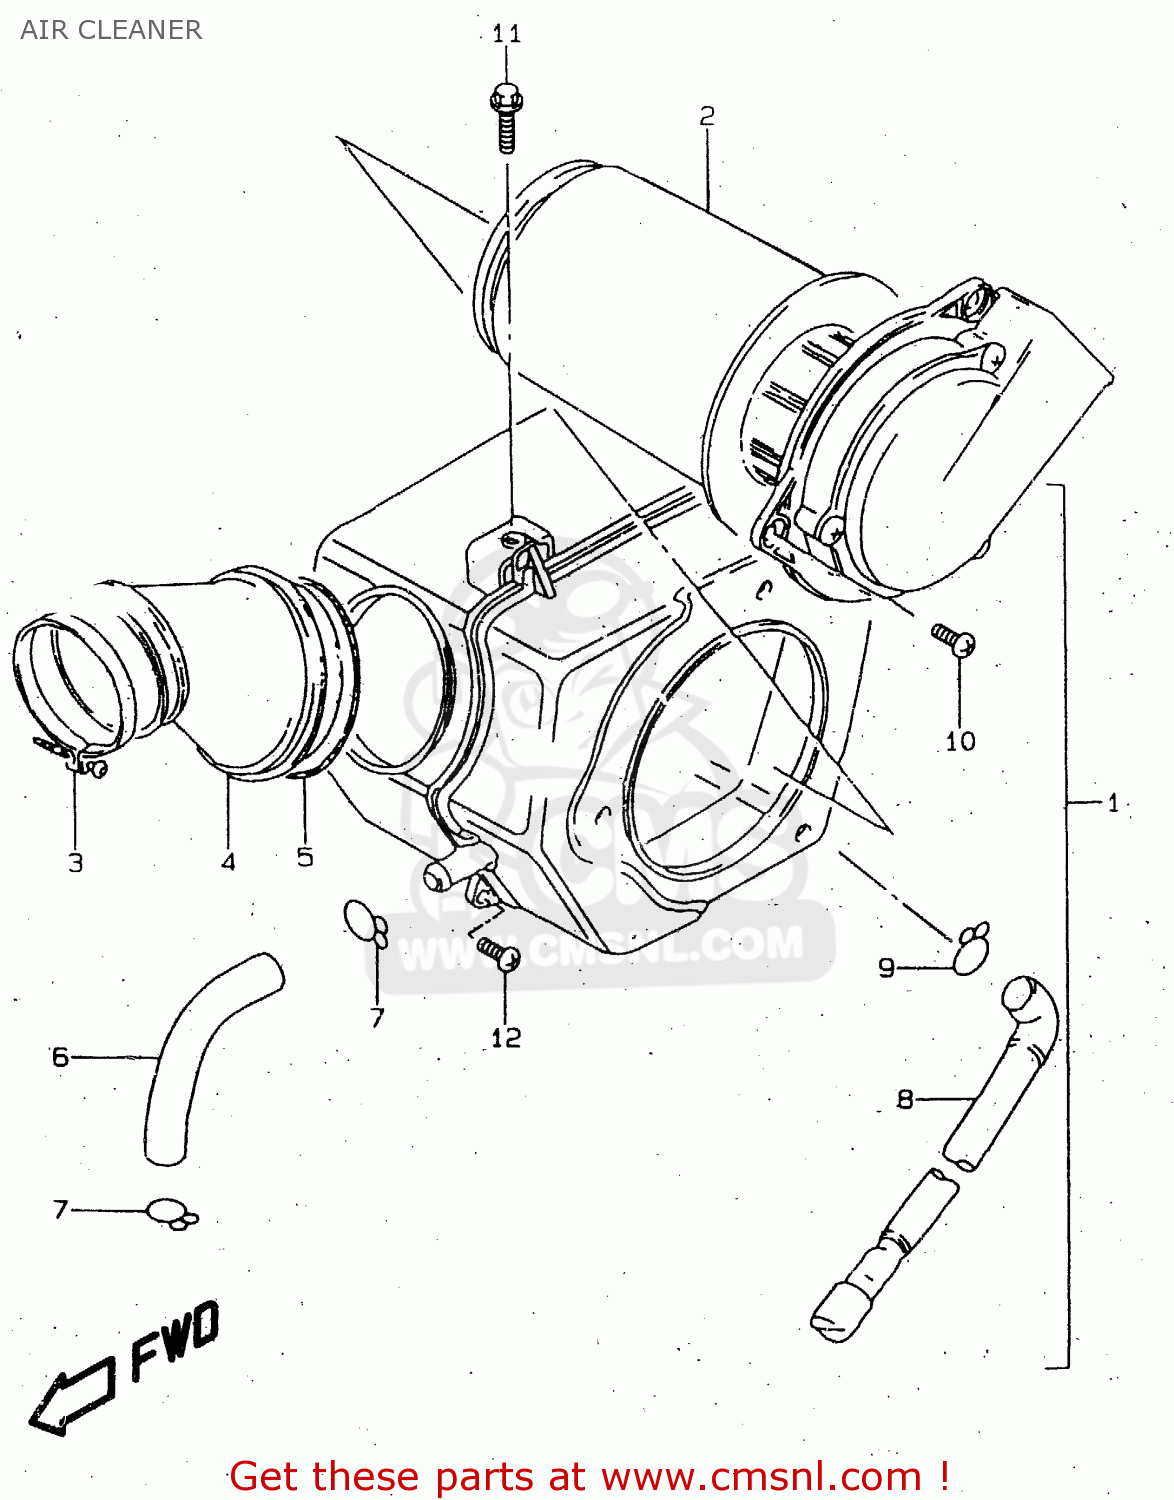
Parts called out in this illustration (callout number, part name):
1	CLEANER ASSY,AIR
2	FILTER
3	CLAMP
4	TUBE,OUTLET
5	CLAMP,AIR CLEANER SIDE
6	TUBE,BREATHER
7	CLIP
8	TUBE,DRAIN
9	CLIP
10	SCREW
11	BOLT
12	BOLT
